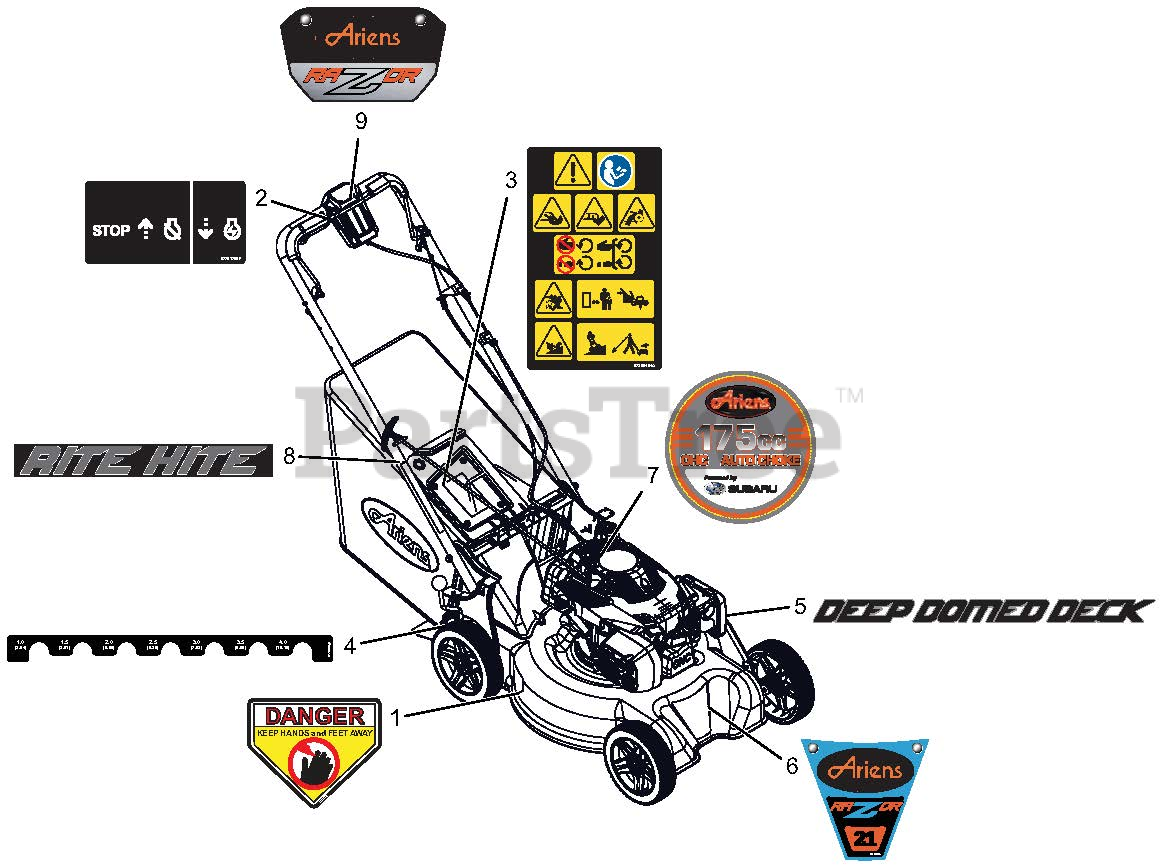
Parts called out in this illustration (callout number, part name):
1	DECAL, DANGER
2	DECAL - ENGINE CONTROL
3	DECAL,MAIN SAFETY_WAW LM
4	DECAL, HOC
5	DECAL, DEEP DOME DECK
6	DECAL, ARIENS RAZOR STYLE
7	DECAL, ENGINE STYLE, ARIENS CE
8	DECAL, RITE HITE
9	DECAL, ARIENS RAZOR - SMALL
